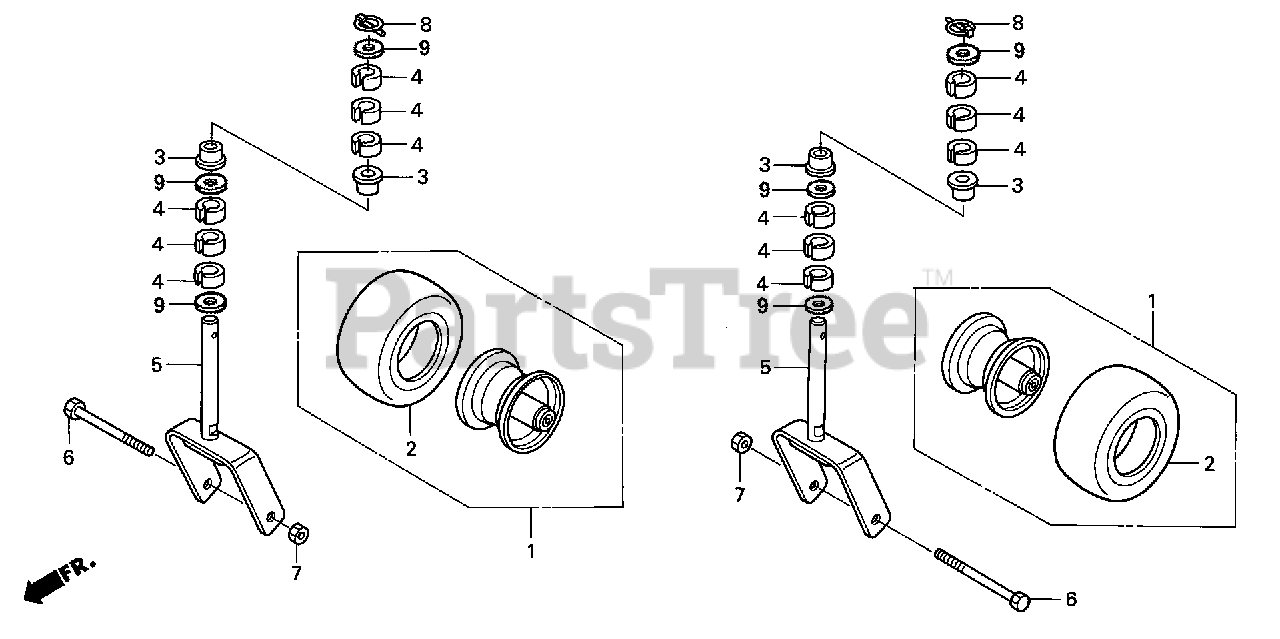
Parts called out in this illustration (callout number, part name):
1	WHEEL ASSY., FR. (9X3.5-4)
2	TIRE (9X3.5-4)
3	BUSHING, CASTER TUBE
4	COLLAR, CASTER TUBE
5	ARM, GAUGE ROLLER
6	BOLT, HEX. (1/2-13X6")
7	NUT, CENTERLOCK (1/2"-13")
8	PIN (1/4")
9	BUSHING (1")
